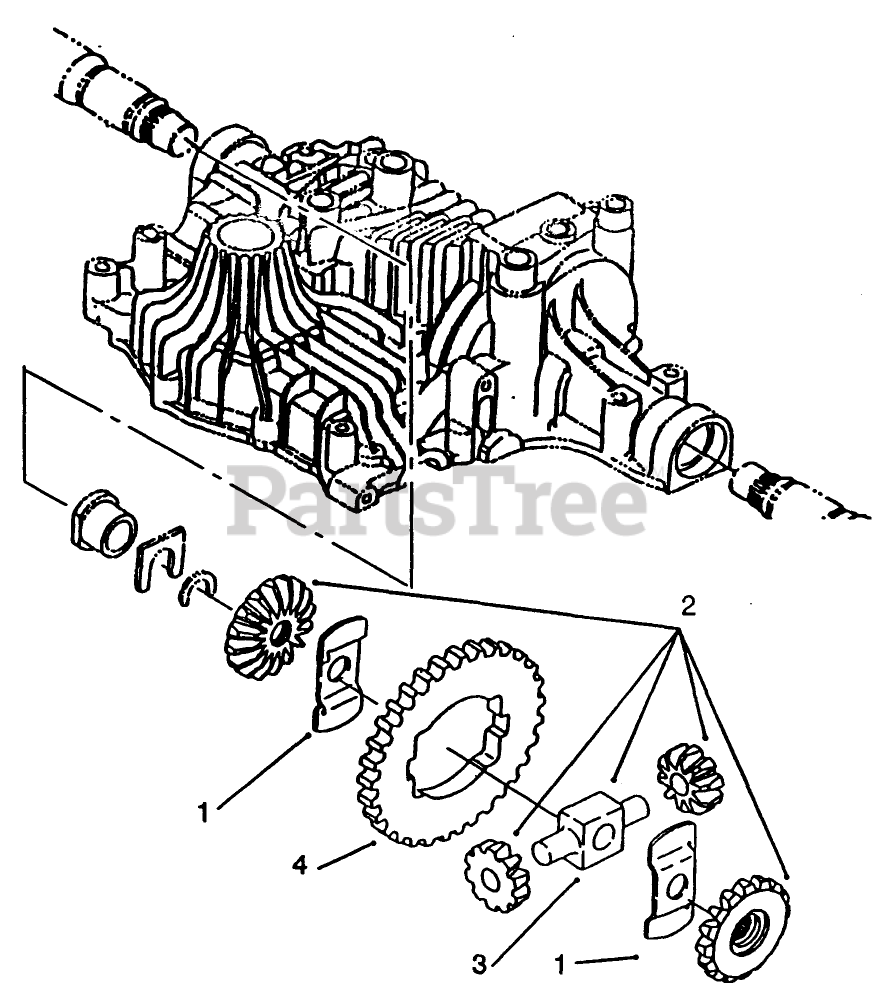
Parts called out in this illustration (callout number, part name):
1	WASHER-THRUST
3	SHAFT - PINION
4	GEAR - FINAL
